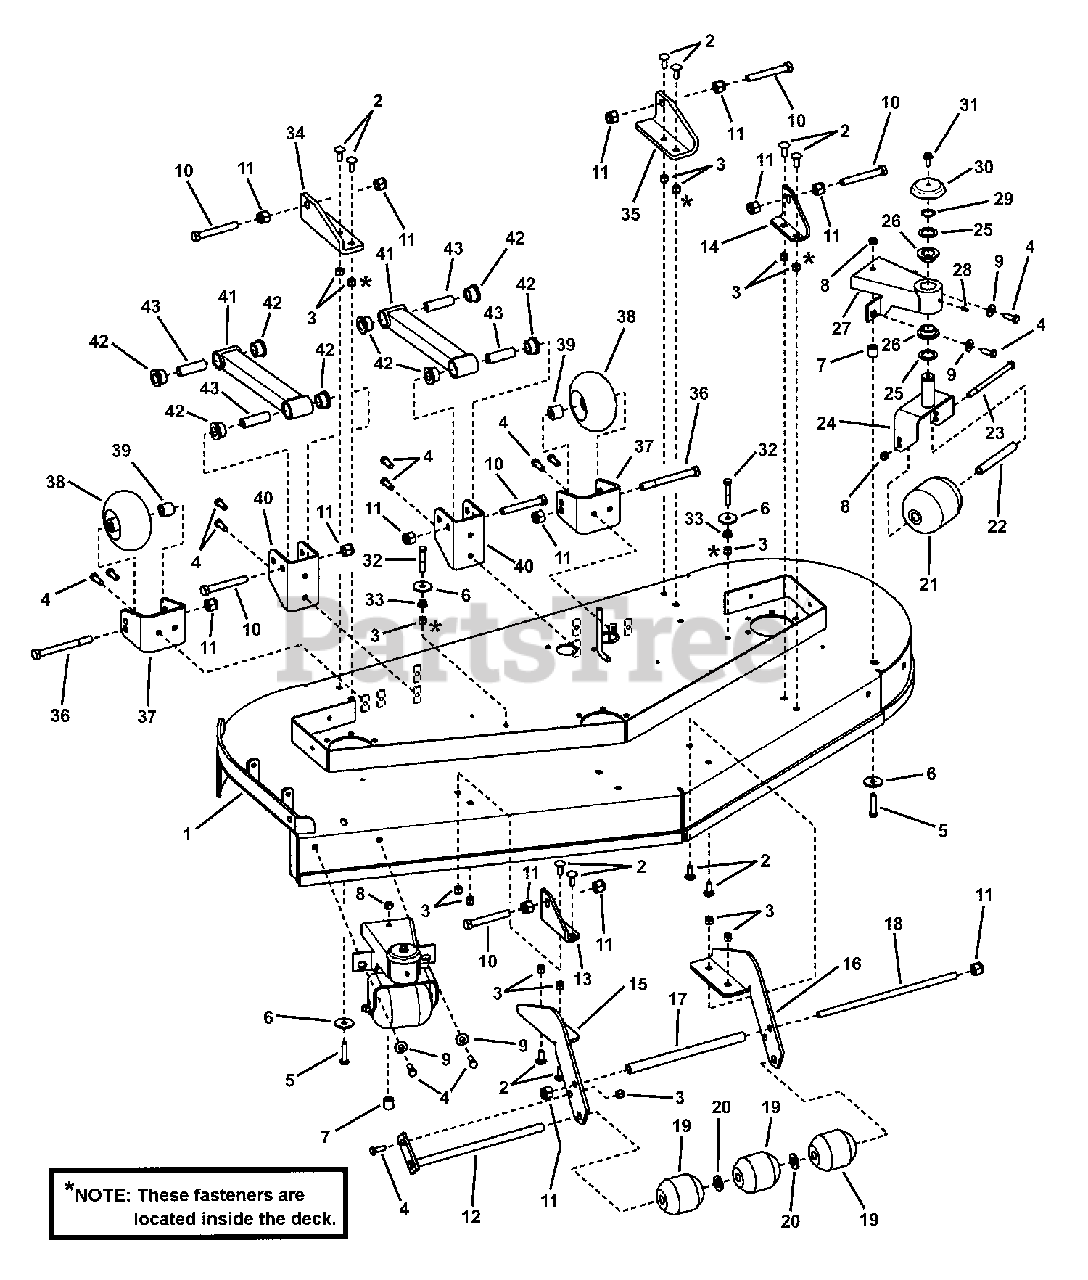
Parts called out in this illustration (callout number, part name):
1	WELDMENT, 61" Deck, NZMX
2	BOLT, 3/8-16 x 1" Square Neck Carriage, GR 5
3	NUT, 3/8-16 HEX NYLON LOCK
4	BOLT, 3/8-16 X 1" GD5 CZ
5	SCREW, 3/8-16 x 1-3/4" Hex Head Cap, GR 5
6	WASHER, .406 x 1.50 x .120 Flat
7	SPACER, 3/4 O.D. x 13/32 I. D. x 3/4" long
8	NUT, 3/8-16 Hex Center Lock
9	WASHER, 3/8" USS
10	BOLT, 1/2-13 x 3-3/4" Hex Head Cap
11	NUT, 1/2-13 Hex Nyloc
12	WELDMENT, Pivot Pin
13	BRACKET, RH Front
14	BRACKET, LH Front
15	FRONT ROLLER BRKT, RH
16	FRONT ROLLER BRKT, LH
17	TUBE, Roller
18	ROD, Roller (1/2-13 Threaded)
19	ROLLER, Low Density Polyethylene
20	WASHER, 5/8" Flat SAE
21	ROLLER 3-3/4 Dia. x 4-13/16" long
22	TUBE, Axle
23	BOLT, 3/8-16 X 6" GD5 CZ
24	WELDMENT, Caster, Gauge Wheel
25	BUSHING, 1" Machine
26	BUSHING, Idler (Powdered Metal)
27	WELDMENT, Gauge Wheel Support
28	LUBE FITTING, 3/16"
29	RING, 1" External Retaining
30	CAP, Caster Shaft
31	SCREW, 5/16-18 x 3/4" Hex Washer Self-Tap
32	BOLT, 3/8-16 X 2, GD5, CZ
33	NUT, 3/8-16 HEX SERRATED FLANGE
34	BRACKET, RH Rear
35	BRACKET, LH Rear
36	BOLT, 1/2-13 X 5 GD5 YZ
37	BRACKET, Gauge Wheel
38	GAUGE WHEEL, Polyethylene
39	SPACER, Gauge Wheel
40	BRACKET, Stabilizer
41	WELDMENT, Pusher Bar
42	BUSHING- Suspension
43	SLEEVE, Suspension
